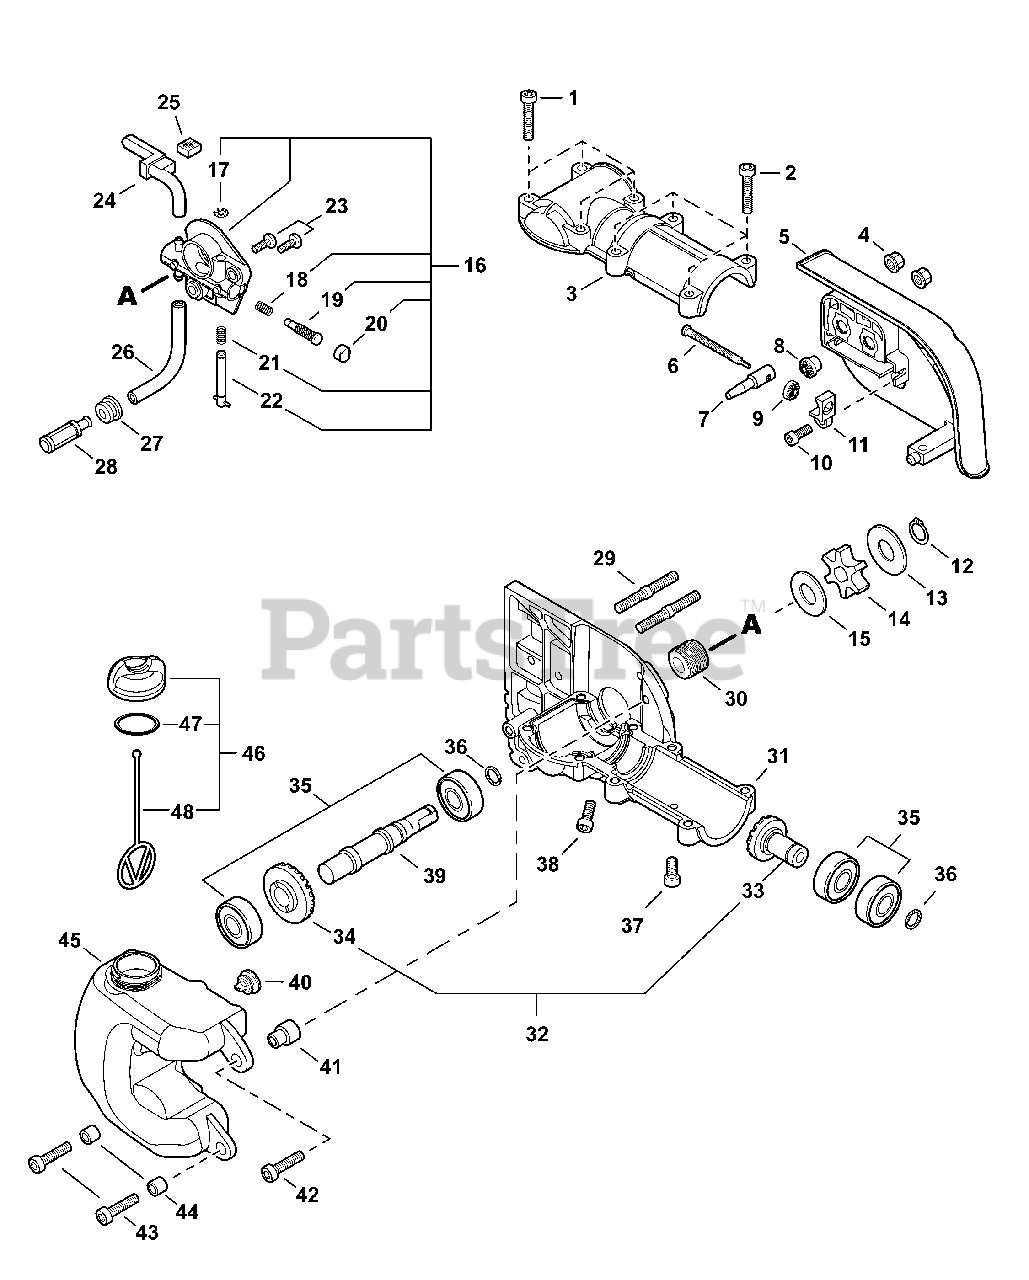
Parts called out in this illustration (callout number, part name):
1	BOLT, TORX 5×25
2	BOLT, TORX 5×25
3	COVER, GEAR CASE
4	NUT, FLANGE M6
5	GUARD, SPROCKET
7	TENSIONER, CHAIN
8	GEAR - 14 TOOTH
9	GEAR - 14 TOOTH
10	SCREW 4
11	COLLAR 8
12	RING, SNAP
13	WASHER 10
14	SPROCKET, DRIVE
15	WASHER 10.2×24.5×1.2
16	AUTO-OILER ASSY
19	PLUNGER ASSY
20	CAP, PLUNGER
22	ADJUSTER, OILER
23	BOLT, TORX 5×10
24	PIPE, OIL OUTLET
25	PAD, FOAM
26	PIPE 3×6×70
27	GROMMET
28	FILTER, OIL
29	BOLT, STUD 6
30	GEAR, WORM
31	CASE, GEAR
32	GEAR SET
33	GEAR, BEVEL
34	GEAR, BEVEL - 23 TOOTH
35	BEARING, BALL
36	RING, SNAP Ø12
37	BOLT, TORX 5×10
38	BOLT, TORX 5×10
39	SHAFT, GEAR
40	VENT ASSY
41	COLLAR 6
42	BOLT, TORX 5×25
43	BOLT, TORX 5×20
44	SPACER 6.2×7.8×6
45	TANK, OIL
46	CAP ASSY
47	O-RING 18
48	CONNECTOR, CAP L= 60 MM
